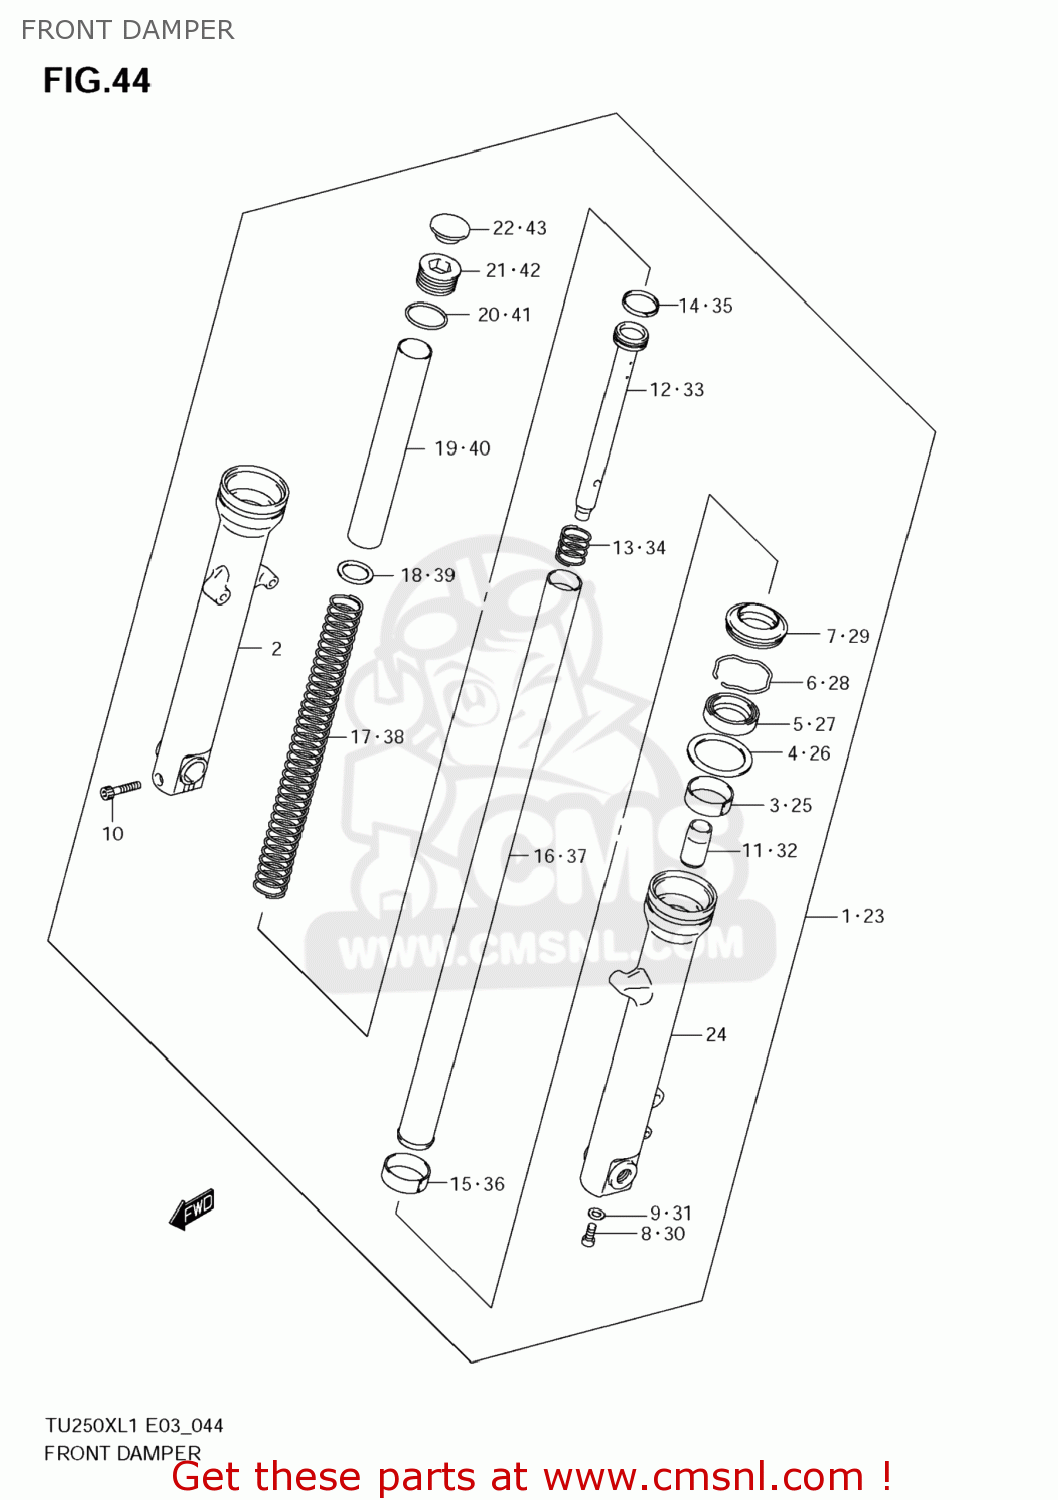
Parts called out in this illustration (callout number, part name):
1	DAMPER ASSY,FR FORK,R
2	TUBE,OUTER,R
3	BUSH,GUIDE
4	SPACER,SEAL
5	OIL SEAL,FRONT FORK
6	RING,STOPPER
7	SEAL,DUST
8	BOLT(8X27)
9	GASKET (NAS)
10	BOLT
11	PIECE,OIL LOCK
12	CYLINDER
13	SPRING,REBOUND
14	RING,PISTON
15	BUSH,SLIDE
16	TUBE,INNER
17	SPRING,MAIN
18	JOINT,SPRING
19	SPACER,SPRING
20	O RING
21	BOLT,FORK
22	CAP,FORK
23	DAMPER ASSY,FR FORK,L
24	TUBE,OUTER,L
25	BUSH,GUIDE
26	SPACER,SEAL
27	OIL SEAL,FRONT FORK
28	RING,STOPPER
29	SEAL,DUST
30	BOLT(8X27)
31	GASKET (NAS)
32	PIECE,OIL LOCK
33	CYLINDER
34	SPRING,REBOUND
35	RING,PISTON
36	BUSH,SLIDE
37	TUBE,INNER
38	SPRING,MAIN
39	JOINT,SPRING
40	SPACER,SPRING
41	O RING
42	BOLT,FORK
43	CAP,FORK
